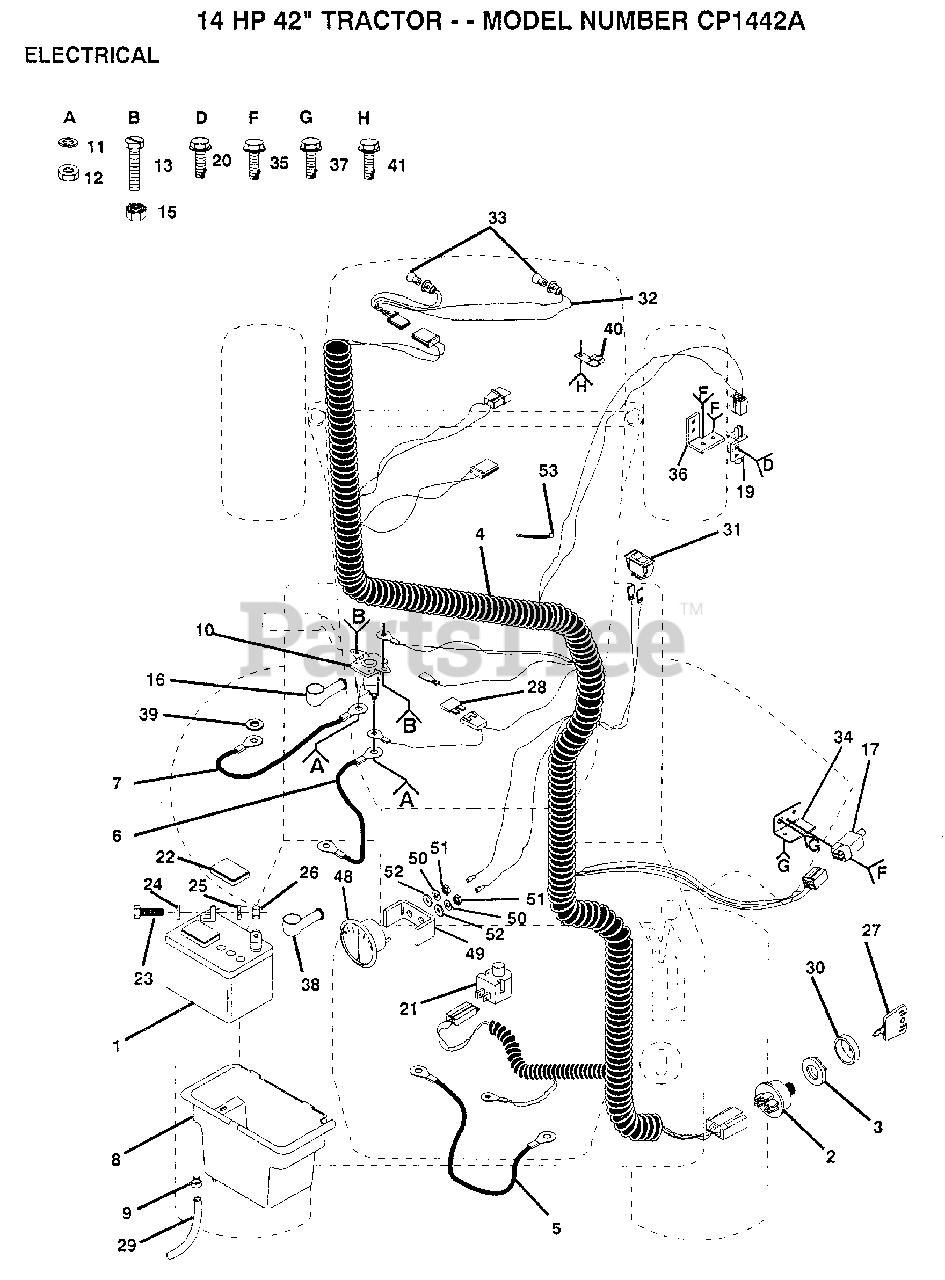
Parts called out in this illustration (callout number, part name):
3	NUT IGNITION
4	HARNESS.IGNITION
5	CABLE T
7	"CABLE T, BATTERY"
8	BTRY CASE W/O LID
9	HOSE CLAMP T
12	NUT
13	BOLT HXHD FIN
15	NUT HXKEP 1/4X20
17	SWITCH INTERLOCKT
19	SWITCH-INTER. GT
20	SCREW
21	SWITCH SEAT
22	"CAP,BATTERY "
23	BOLT LT
24	WASHER
25	LOCKWASHER
27	KEY
28	FUSE HYT
29	TUBE T
31	SWITCH LT
32	"HARNESS,LIGHT SOC"
34	BRACKET LT
35	SCREW
36	SWITCH BRACKET
37	SCREW
39	LOCKWASHER
40	CLIP T
41	SCREW LT
48	AMMETER T
52	WASHER
53	WIRE TIE
